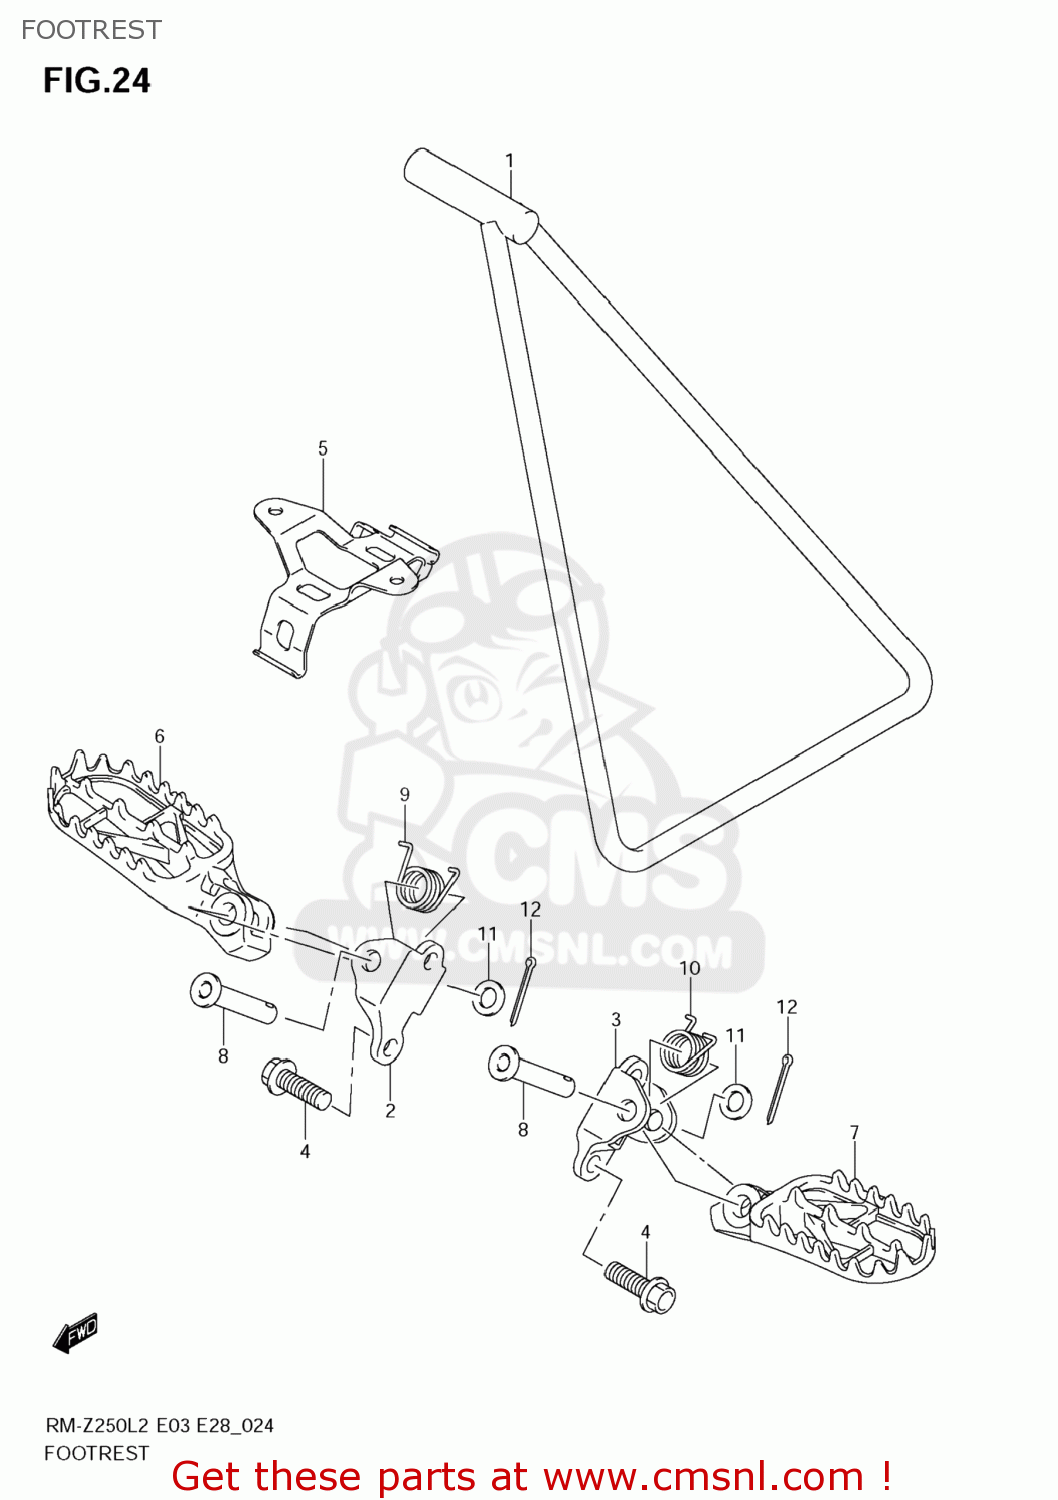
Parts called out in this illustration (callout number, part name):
1	STAND
2	BRACKET,FOOTREST,R
3	BRACKET,FOOTREST,L
4	BOLT(10X25)
5	BRACKET,ECU
6	FOOTREST,R
7	FOOTREST,L
8	PIN(10X41.5)
9	SPRING
10	SPRING
11	WASHER(10.5X18X1)
12	PIN
